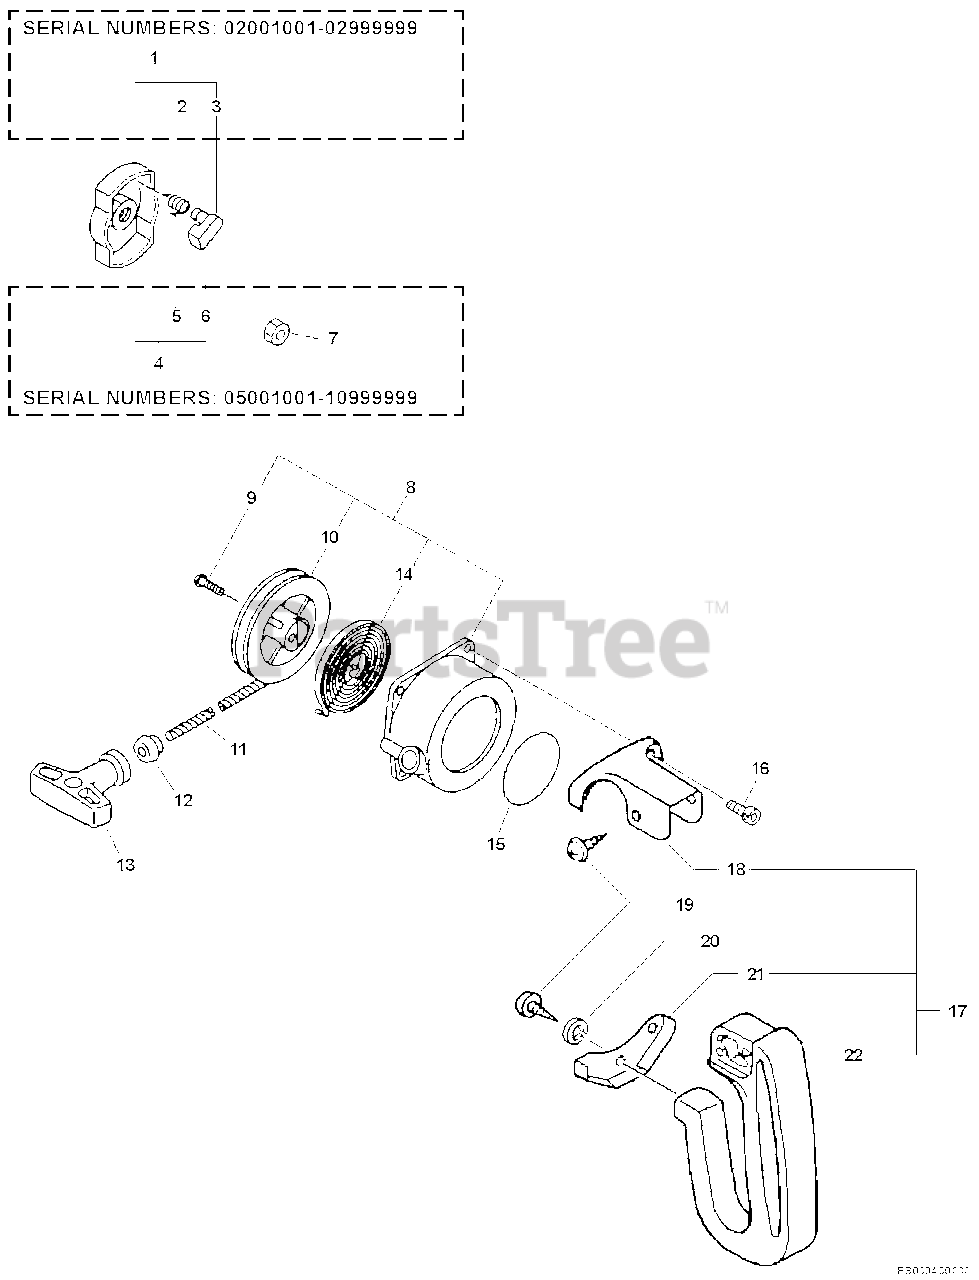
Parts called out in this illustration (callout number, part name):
1	STARTER PAWL ASSY
2	SPRING, RETURN
3	PAWL, STARTER - BLACK
4	STARTER PAWL ASSY
5	SPRING, RETURN
6	PAWL, STARTER - BLACK
8	STARTER ASSY
10	REEL, ROPE
11	ROPE, STARTER - 3X1000
12	GUIDE, ROPE
13	GRIP, STARTER
14	SPRING, REWIND
15	LABEL - ECHO
16	SCREW - 4X16
17	HANDLE ASSY - REAR
18	BRACKET, HANDLE - UPPER
19	SCREW - 5X16 -- TAPPING
20	LOCKWASHER - 5
21	BRACKET, HANDLE - LOWER
22	HANDLE - REAR
